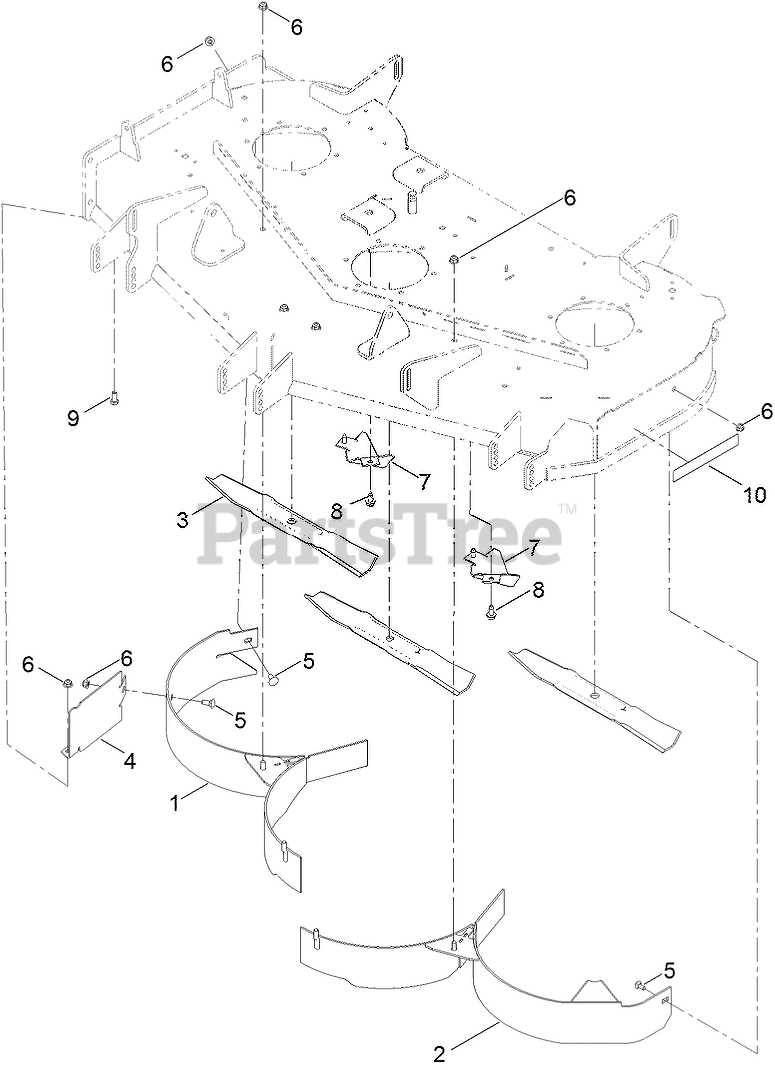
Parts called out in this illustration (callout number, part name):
1	BAFFLE-RECYCLER
2	BAFFLE-RECYCLER
3	BLADE-MULCH, 16.50 INCH
4	GUARD-BAFFLE
5	BOLT-CARR
6	NUT-HF, NI
7	KICKER-FLANGED
8	SCREW-HWHTF
9	SCREW-HH
10	DECAL-RECYCLER
